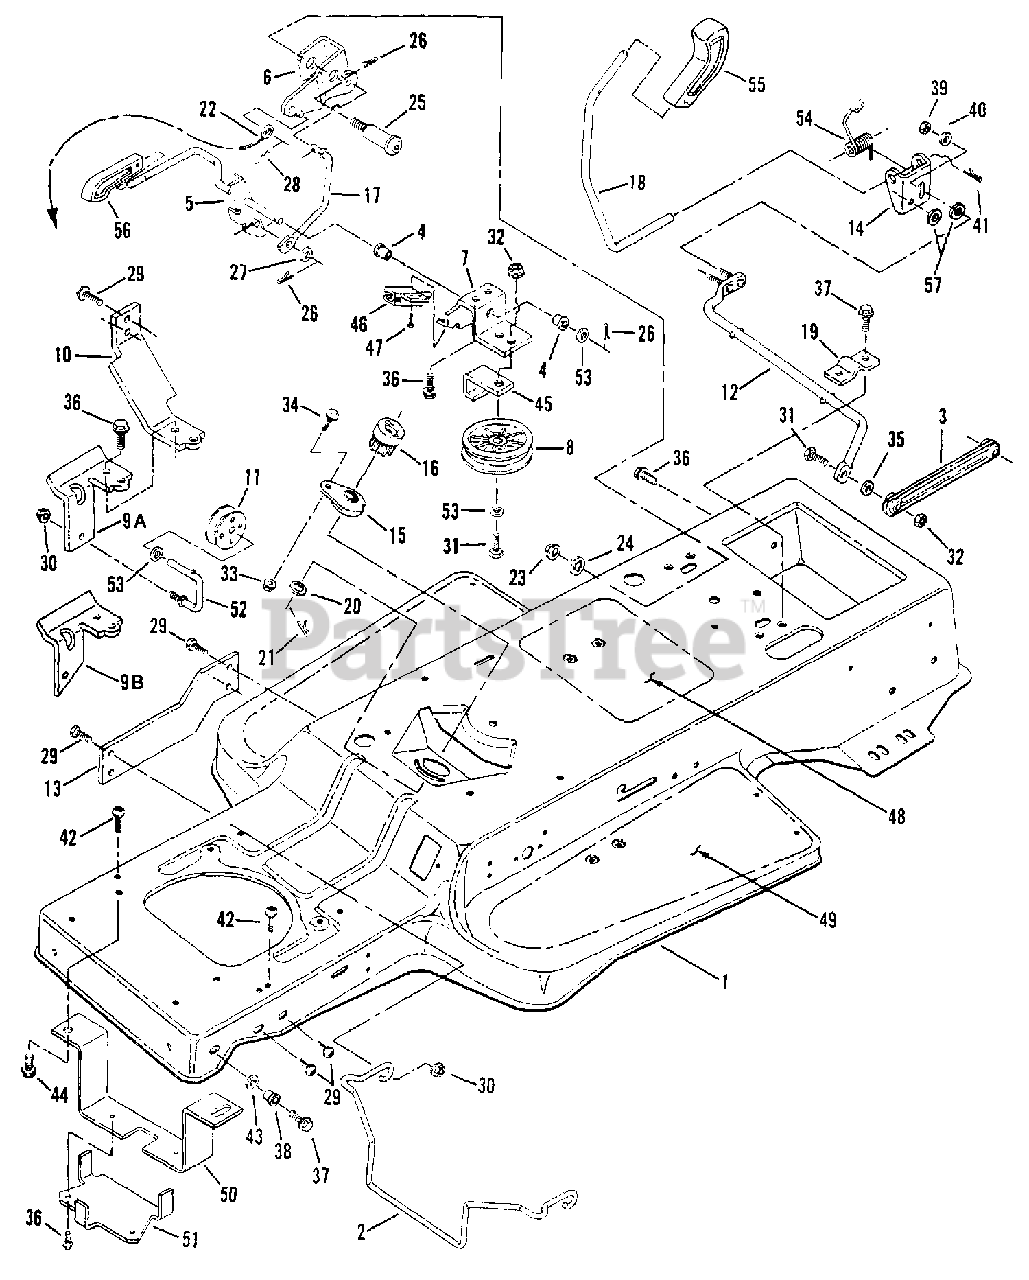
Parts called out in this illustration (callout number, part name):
1	FRAME, Tractor
2	GUIDE, Belt
3	LINK, Shift Lever
4	BUSHING
5	WELDMENT, PTO Lever
6	WELDMENT, PTO Bellcrank
7	SUPPORT, PTO Lever
8	PULLEY
9A	BRACKET, Spool
9B	BRACKET, Spool
10	BRACKET, Torque
11	SPOOL
12	ASSEMBLY, Shift Lever (Lower)
13	BRACE, Frame
14	BRACKET, Shift Lever (Upper)
15	ASSEMBLY, Steering Adjuster
16	GEAR, Steering Pinion
17	ROD, PTO Link
18	LEVER, Shift
20	WASHER, 1/2 Shim
21	PIN, 1/8 x 3/4" Cotter
22	CABLE, Blade (14.32" Long)
22	CABLE, Blade (20.5" Long)
23	NUT, 1/2-13 Hex Flange Lock
24	WASHER, 1/2 Internal Tooth Lock
25	BOLT, 1/2-13 x 2 11/32" Shoulder
26	PIN, 3/32 x 3/4" Cotter
27	WASHER, 3/8" Flat
28	PIN, 3/32 x 1 1/2" Hair Cotter
29	SCREW, 5/16-18 x 5/8" Truss Head
30	NUT, 5/16-18 Hex Flange Lock
31	SCREW, 3/8-16 x 1 1/2" Hex Head Cap
32	NUT, 3/8-16 Hex Center Lock
33	NUT, 1/4-20 Hex Flange Lock
34	BOLT, 1/4-20 x 5/8" Short Neck Carriage
35	SPACER
36	SCREW, 5/16-18 x 5/8" Self-Tapping
37	SCREW, 5/16-18 x 1 1/4" Self-Tapping
38	BUSHING, Flange
39	NUT, 1/4-20 Hex Flange Lock
40	WASHER, 1/4 Flat
41	PIN, 5/32 x 1" Cotter
42	SCREW, 5/16-18 x 7/8" Truss Head
43	WASHER, 5/16 Flat
44	BOLT, 5/16-18 x 3/4" Hex Flange Lock
45	GUIDE, Belt
46	SWITCH, Blade Engagement
47	SCREW, #10-24 x 1/2" Hex Washer Self-Tap (Torx)
48	DECAL, Instruction/Safety
49	PAD, Foot Sandpaper
50	BRACKET, Belt Guide
51	GUIDE, Engine Belt
52	ROD, Spool Pivot
53	WASHER, 3/8" Flat
54	SPRING, Shift Lever
55	KNOB, Deck Lift Lever
56	KNOB, Deck Engagement
57	WASHER, 1/4 Internal Tooth Lock
